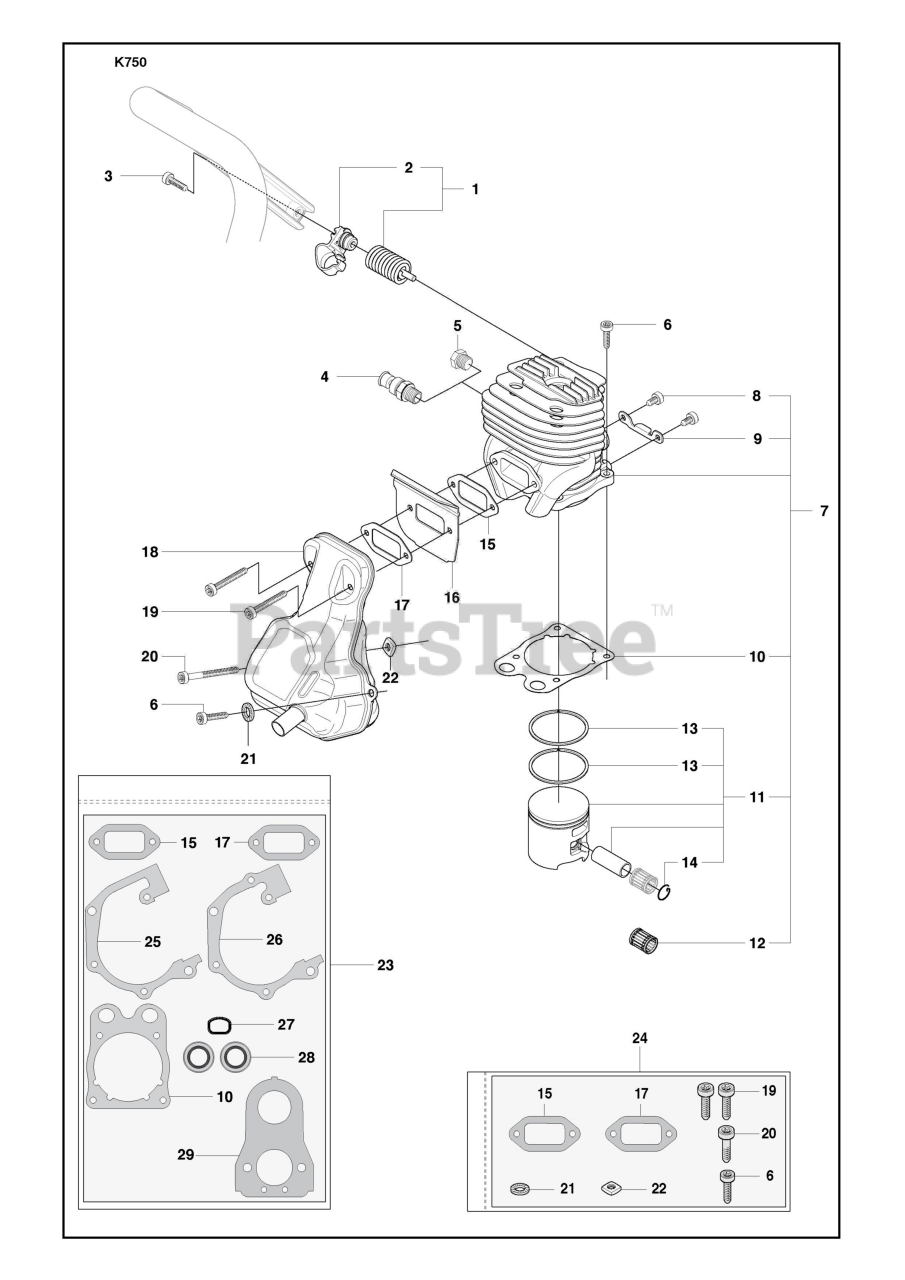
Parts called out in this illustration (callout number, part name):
1	Vib.Insulator
2	Spring Retainer
4	Decompression Valve
7	Cylinder Assy
10	Cylinder Base Gasket
11	Piston Assy
12	Needle Bearing
13	Piston Ring
16	Cooling Plate
17	Gasket Muffler
18	Muffler
23	Gasket Kit
24	Muffler Mounting Kit
25	Gasket Crankcase
26	Gasket Crankcase
28	Sealing Ring
29	Gasket Carburettor
